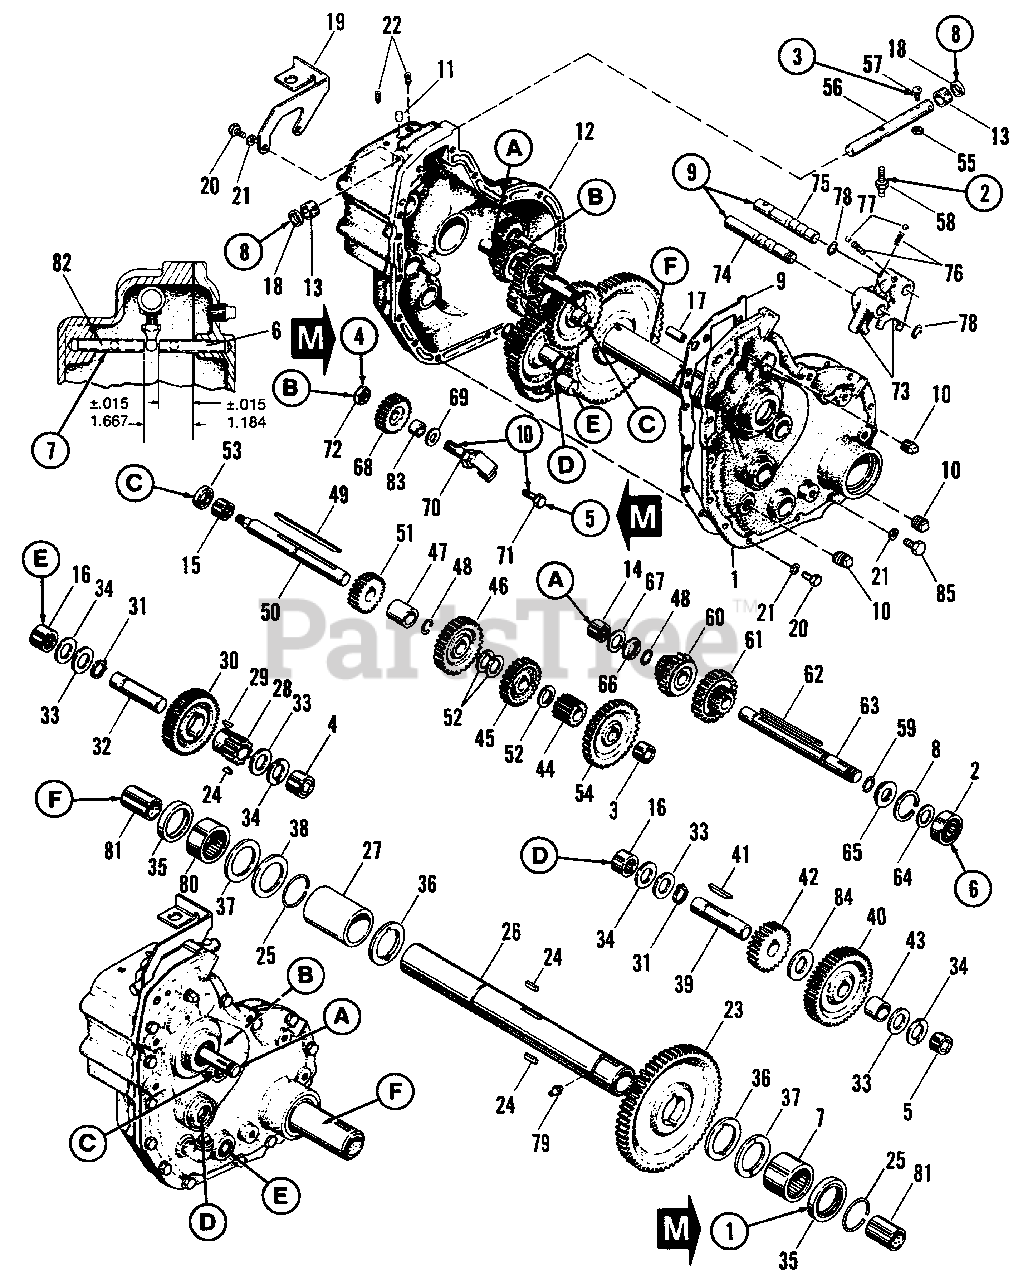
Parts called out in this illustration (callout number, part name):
1	COVER, Gear Case
2	BEARING, Ball
3	BEARING, Needle
4	BEARING, Needle
5	BEARING, Needle
6	ROLL PIN ASSY.
7	BEARING, Needle
8	RING, Retaining
9	GASKET, Gear Case
10	PLUG, Pipe, Sq. Hd., 3/8
12	GEAR CASE ASSY.
13	SPACER, Diff.
14	BEARING, Needle
15	BEARING, Needle
16	BEARING, Needle
17	PIN, Spring, 3/8 x 1
19	SUPPORT, Switch
20	CAPSCREW, Hex Hd., 5/16-18-x 1
21	LOCKWASHER, 5/16
22	SETSCREW, Skt. Hd., 5/16-18 x 1/2
23	GEAR, Drive
26	TUBE & BUSHING ASSY.
27	SPACER, Axle Tube
28	PINION, 3rd Interm.
29	KEY, Woodruff, #6
30	GEAR, 3rd Interm.
31	RING, Retaining
32	SHAFT, 3rd Interm.
36	WASHER, Axle Tube
37	WASHER, Axle Tube
38	WASHER, Axle Tube
39	SHAFT, 2nd Interm.
40	GEAR, 2nd Interm.
42	PINION, 2nd Interm.
44	PINION, 1st Interm.
45	PINION, Driver III
46	GEAR, Driver II
48	RING, Retaining
50	SHAFT, 1st Interm.
51	PINION, Rev. & IV
54	GEAR, Driven I
55	NUT, Hex, Jam, 5/16-18
56	ROD, Shift
57	BOLT, Carriage, Special
58	STEM, Shift
59	RING, Retaining
60	PINION ASSY., Rev. & II
61	PINION ASSY., I & II
63	SHAFT, Pulley
70	REV. GEAR PIN ASSY.
71	CAPSCREW, Hex, Flange, Whizlock 3/8-16 x 1-1/4
72	LOCKNUT, Hex, 1/2-20
73	FORK, Shift
74	SHAFT, Shifter
75	SHAFT, Shifter, HI-LO
77	BALL, Shiftlock
78	RING, Retaining
79	FITTING, Grease
80	BEARING, Needle
82	ROLL PIN ASSY.
83	SPACER, Rev. Gear
85	CAPSCREW, Hex Hd., 5/16-18 x 1-1/2
